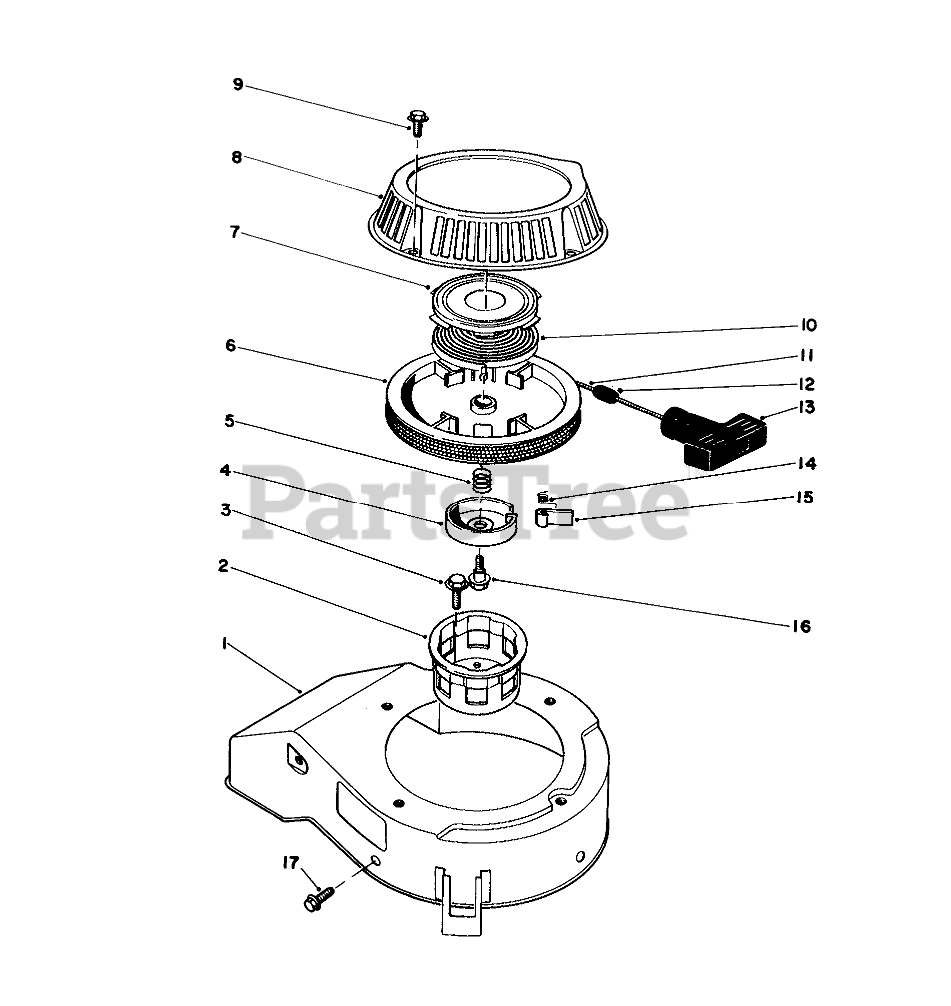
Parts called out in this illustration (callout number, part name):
1	COVER
2	CUP - STARTER
4	RETAINER
5	SPRING
7	Retainer-Recoil Spring
9	SCREW-HHF
10	Spring-Recoil
11	ROPE-STARTER
12	ROPE STOP
13	HANDLE-RECOIL
14	SPRING
